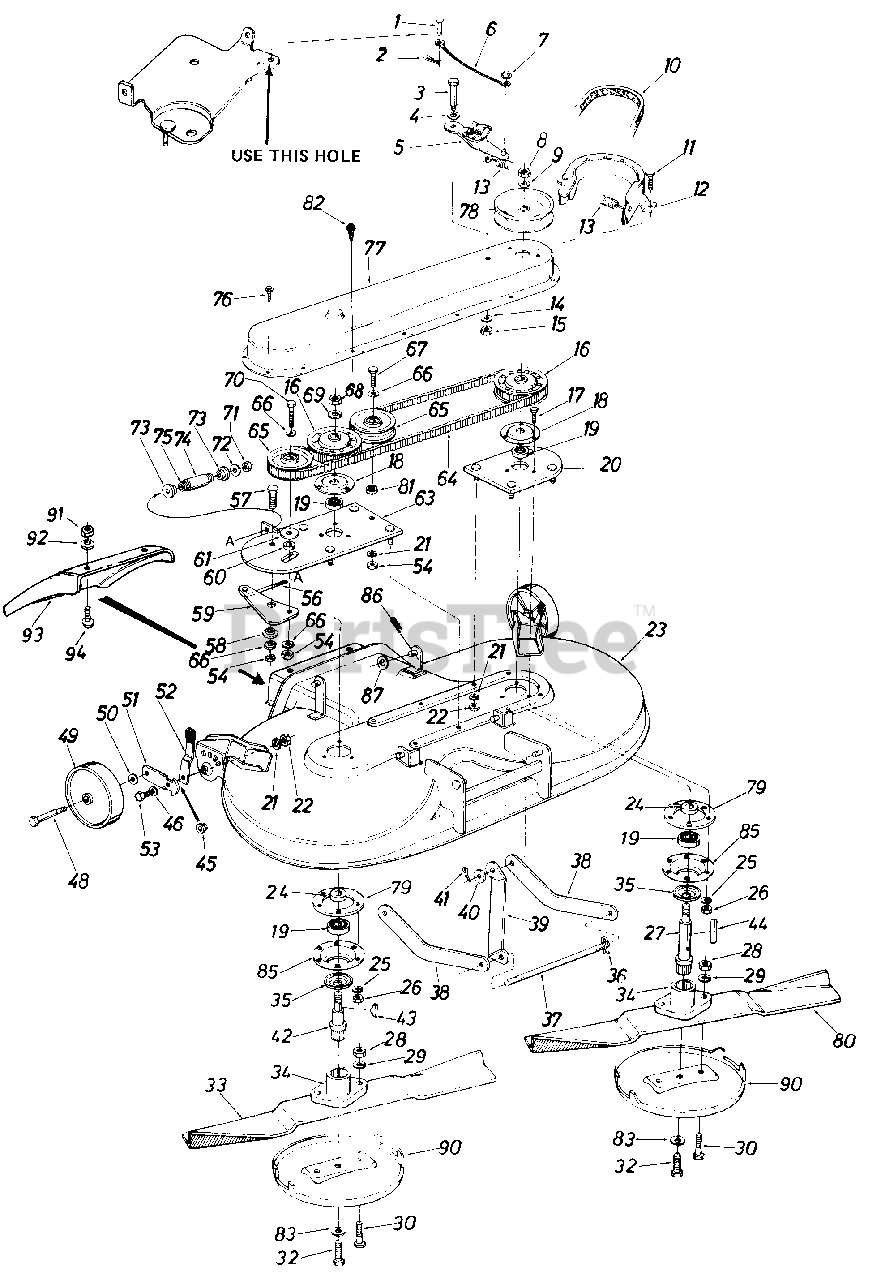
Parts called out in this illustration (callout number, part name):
1	Clevis Pin 1/4" Dia. x 1/2" Lg.
2	Hairpin Cotter 1/4" Dia.
3	Shld. Bolt .437" Dia. x .180" Lg. (5/16-18)
4	Wave Washer 7/16" Scr.
5	Spindle Brake Arm Ass'y.
6	Brake Cable Ass'y.
7	Push Cap 1/4" Stud.
8	Hex Jam Nut 5/8-18 Thd.
9	Bell.-Wash. 5/8" I.D. x 1.25" O.D.
10	"V" Belt
11	Hex Wash. Hd. Self Tap Scr. 1/4-20 x .50" Lg.
12	Belt Guard
13	Extension Spring
14	Bell.-Wash. .340" I.D.
15	Hex Cent. L-Nut 5/16-18 Thd.
16	Sprocket Pulley Ass'y.
17	Hex Bolt 5/16-24 x 1.00" Lg. (Grade 5)
18	Bearing Housing
19	Ball Bearing .787" I.D. x 1.85" O.D.
20	Spindle Plate Ass'y.
21	L.-Wash. 3/8" I.D.*
22	Hex Jam Nut 3/8-"4 Thd.
23	44" R.C. Deck Ass'y.
24	Spacer
25	L.-Wash. 5/16" I.D.*
26	Hex Nut 5/16-24 Thd.*
27	Blade Spindle - L.H.
28	Hex Nut 5/16-24 Thd.*
29	L.-Wash. 5/16" I.D.*
30	Hex Bolt 5/16-24 x 1.00" Lg.
32	Hex Bolt Cent. L.-3/8 x 24 x 88" Lg.
33	22.5" Blade-L.H. Rotation
34	Blade Adapter
35	Bearing Shield
36	Hairpin Cotter
37	Deck Connecting Rod
41	Cotter Pin 3/32" Dia. x 1.00" Lg.*
42	Blade Spindle - R.H.
43	Sq. Key 3/16" x 75" Lg.*
44	Sq. Key 3/16" x 1.50" Lg.*
45	Shoulder Spacer
46	Bell.-Wash. .400" I.D.
48	Shld. Bolt 3/8-16 x 1.41" Lg.
49	Wheel Ass'y. Comp. 6" x 1.38
50	Bell-Wash. 3/8" I.D.
51	Wheel Pivot Bar
52	Spring Lever Ass'y. w/knob
53	Hex Bolt 3/8-24 x 1.25" Lg. Grade 5
54	Hex Cent. L-Nut 3/8-24 Thd.
56	Adjustment Link 5/16-18 x 4-9/1 6" Lg.
57	Hex Bolt 3/8-24 x 1.00"
58	Shld. Spacer.625" I.D.
59	Belt Idler Brkt.
60	Spacer.380" I.D. x .625" O.D. x .265
61	Fl.-Wash. .38" I.D. x 1.37" O.D. x .125
63	Spindle & Idler Mount Plate Ass'y.
64	HTD Twin Power Belt
65	Fl.-Idler Pulley 3.50" O.D.
66	Bell.-Wash. .38" I.D.
67	Hex Bolt 3/8-24 x 1.75" Lg. (Grade 5)
68	Hex Jam Nut 5/8-18 Thd.*
69	Bell.-Wash. 5/8" I.D.
70	Hex Bolt 3/8-24 x 2.00" Lg.
71	Hex Insert L.-Nut5/16-18 Thd.
72	Fl.-Wash. 344" I.D. x 1.125" O.D. x .125
73	Shld. Spacer.625" I.D.
74	Spacer-Adj. Bolt
75	Compression Spring
76	Hex Wash. Hd. Self Tap Scr. 1/4-20 x .50" Lg.
77	Belt Cover
78	Deck Drive Pulley
79	Deck Reinforcement Plate
80	22.5" Blade-R.H. Rotation
81	Fl.-Wash. .38" I.D. x 1.00" O.D.
82	Hex Wash. Hd. Self Tap-Scr. 1/4-20 x .75" Lg.
83	L.-Wash. 3/8" I.D. Heavy Duty
86	Hairpin Cotter
87	Fl.-Wash. 1/2" I.D.
90	Anti Scalp Plate
91	Hex Nut 1/4-20 Thd.*
92	L.-Wash. 1/4" I.D.*
93	Chute Deflector
94	Truss Mach. Scr. 1/4-20 x .50" Lg.
